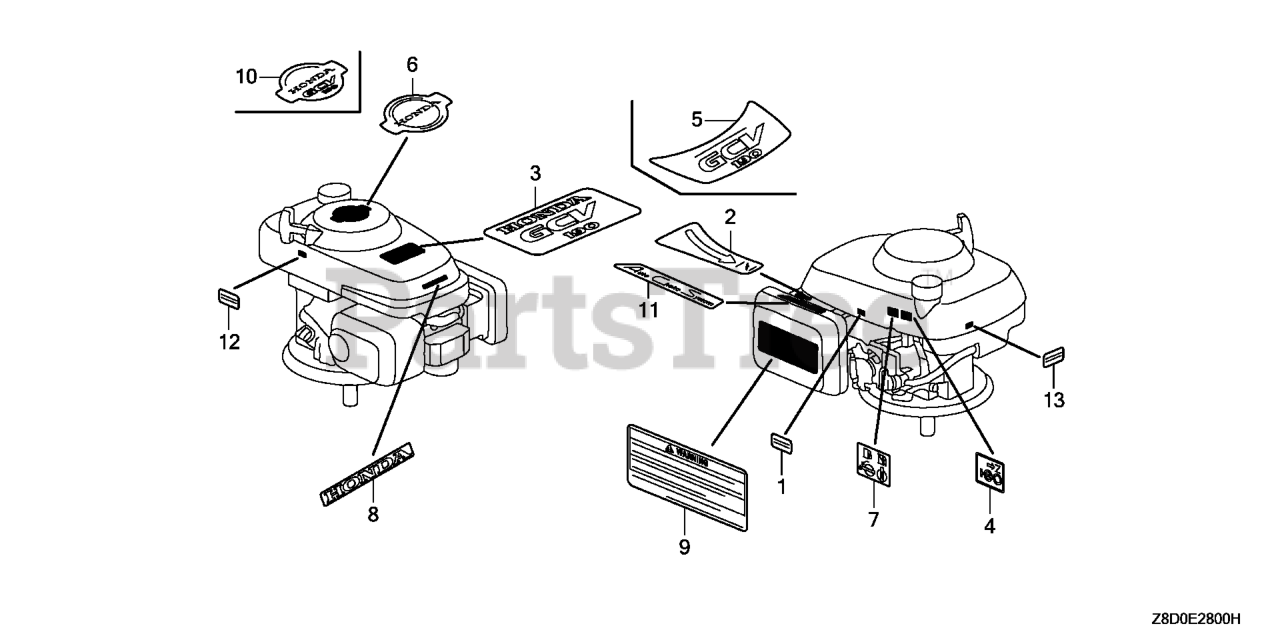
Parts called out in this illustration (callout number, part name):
4	MARK, CHOKE
5	MARK, EMBLEM (GCV190)
6	MARK, RECOIL COVER
7	MARK, FUEL PETCOCK CAUTION
9	MARK, OPERATOR CAUTION (ENGLISH)
12	LABEL, WARNING (NOT CERTIFIED FOR SALE)
